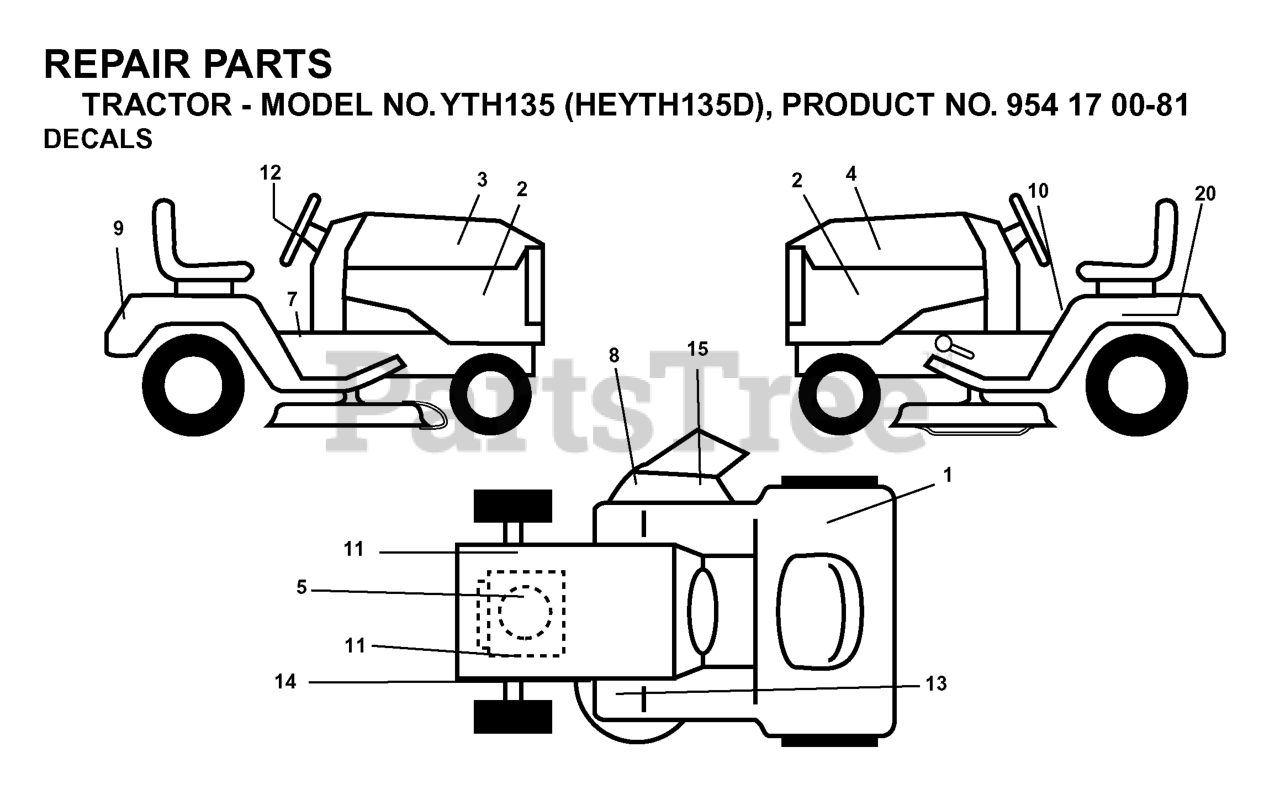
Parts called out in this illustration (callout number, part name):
1	Decal, Fender 100 DB/CE
2	DECAL PNL SIDE
7	DECAL PARK BRAKE
8	DECAL.INTERNATIONL.CUTFINGER
9	DECAL FENDER HUSQ
10	DECAL READ OWNER'S MAN SYMS
12	DECAL.WHEEL.STEERING.HUSQ.PERM
13	DECAL
14	DECAL V BELT SCHEMATIC
15	DECAL DECK "B" 42"
20	DECAL BTRY SYMBOLS
